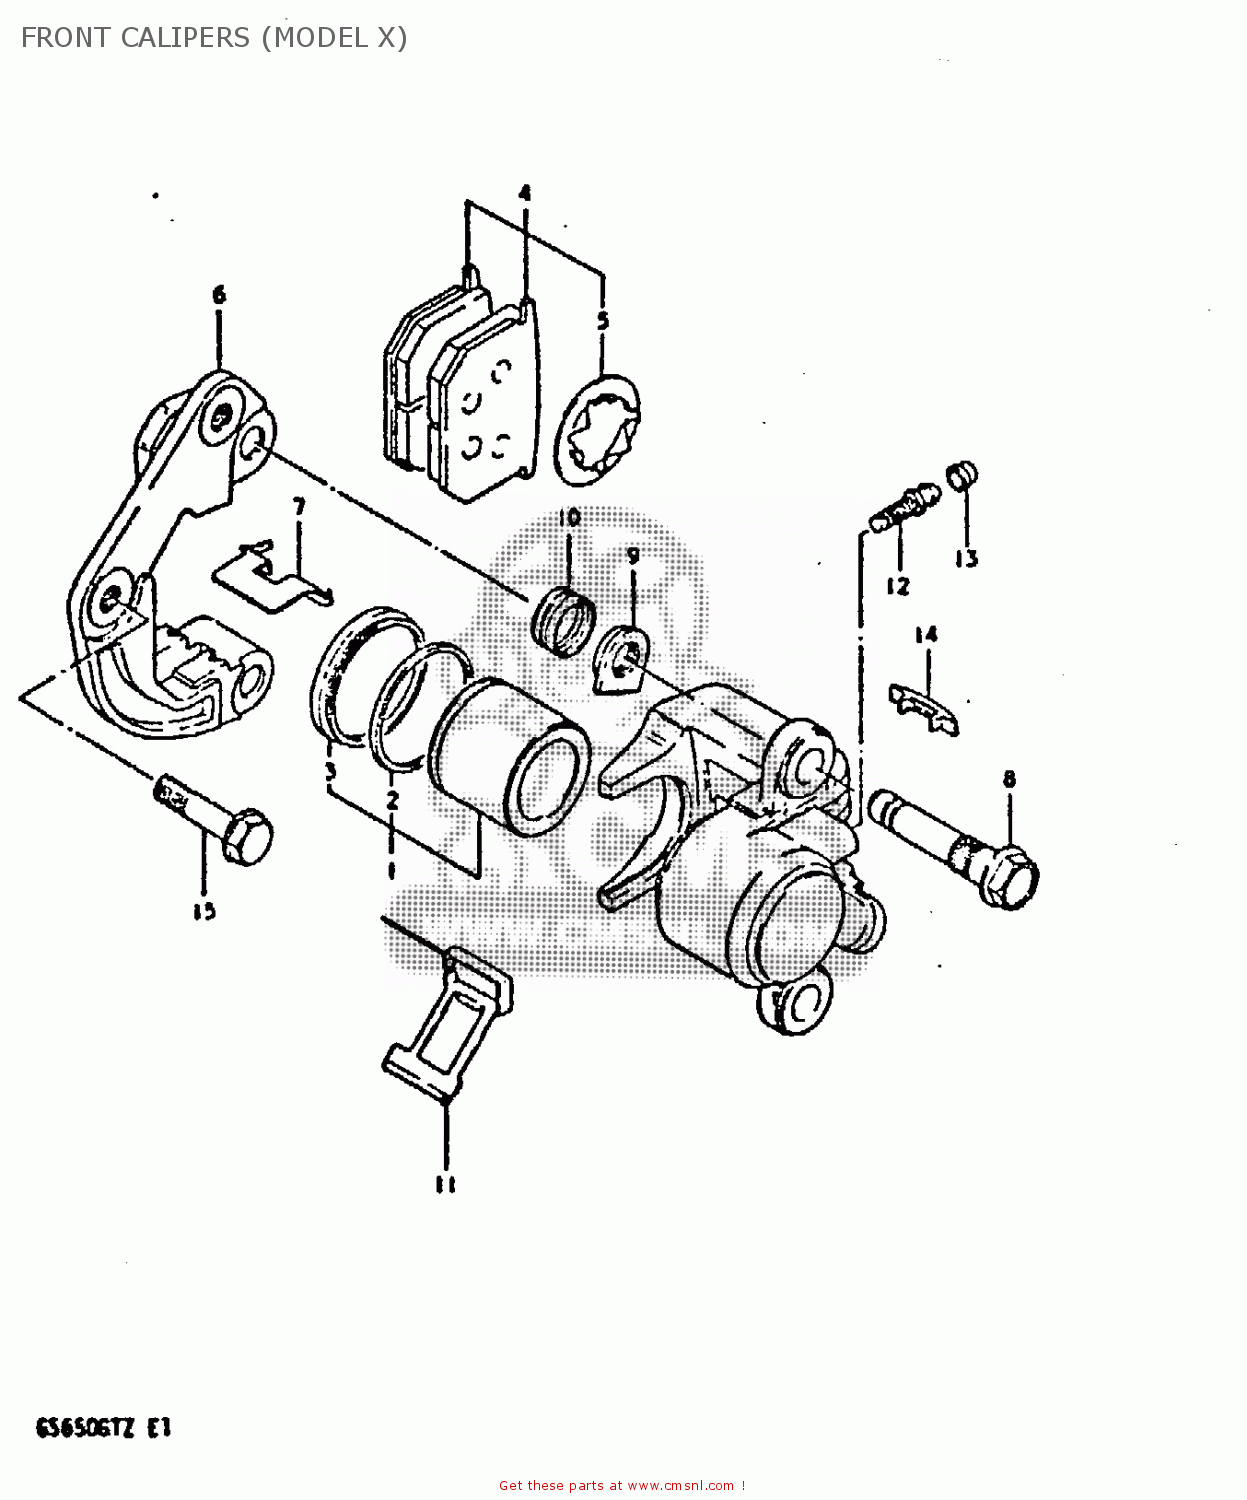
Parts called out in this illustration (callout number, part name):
1	PISTON SET
2	SEAL,PISTON
3	BOOT,PISTON
4	PAD & SHIM SET (MCA)
5	SHIM,PAD
6	HOLDER,CALIPER,LEFT
7	GUIDE, PAD
8	AXLE,CALIPER
9	NUT,CALIPER AXLE
10	BOOT
11	SPRING
12	BREATHER
13	CAP,BLEEDER PL
14	COVER,INDICATOR
15	BOLT(10X37)
